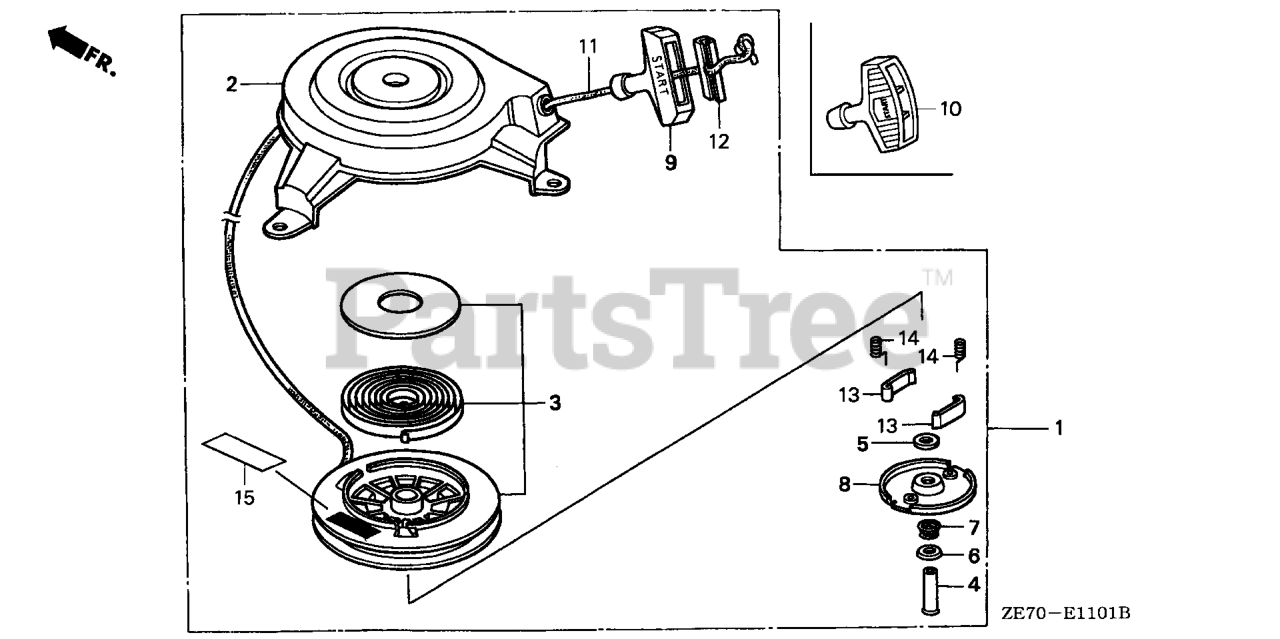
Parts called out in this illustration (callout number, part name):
1	STARTER,RECOIL(COO)
2	HOUSING ASSY. (NA USE ALT:28400-ZG9-803)
3	PULLEY & SPRING ASSY.
4	PIN, CENTER
5	PLATE A, FRICTION
6	PLATE B, FRICTION (NOT AVAILABLE)
7	SPRING, FRICTION
11	ROPE (#4.5X96")
12	HANDLE, REINFORCEMENT
13	RATCHET, STARTER
14	SPRING, DOG
15	MARK, PARTS NUMBER (NOT AVAILABLE)
